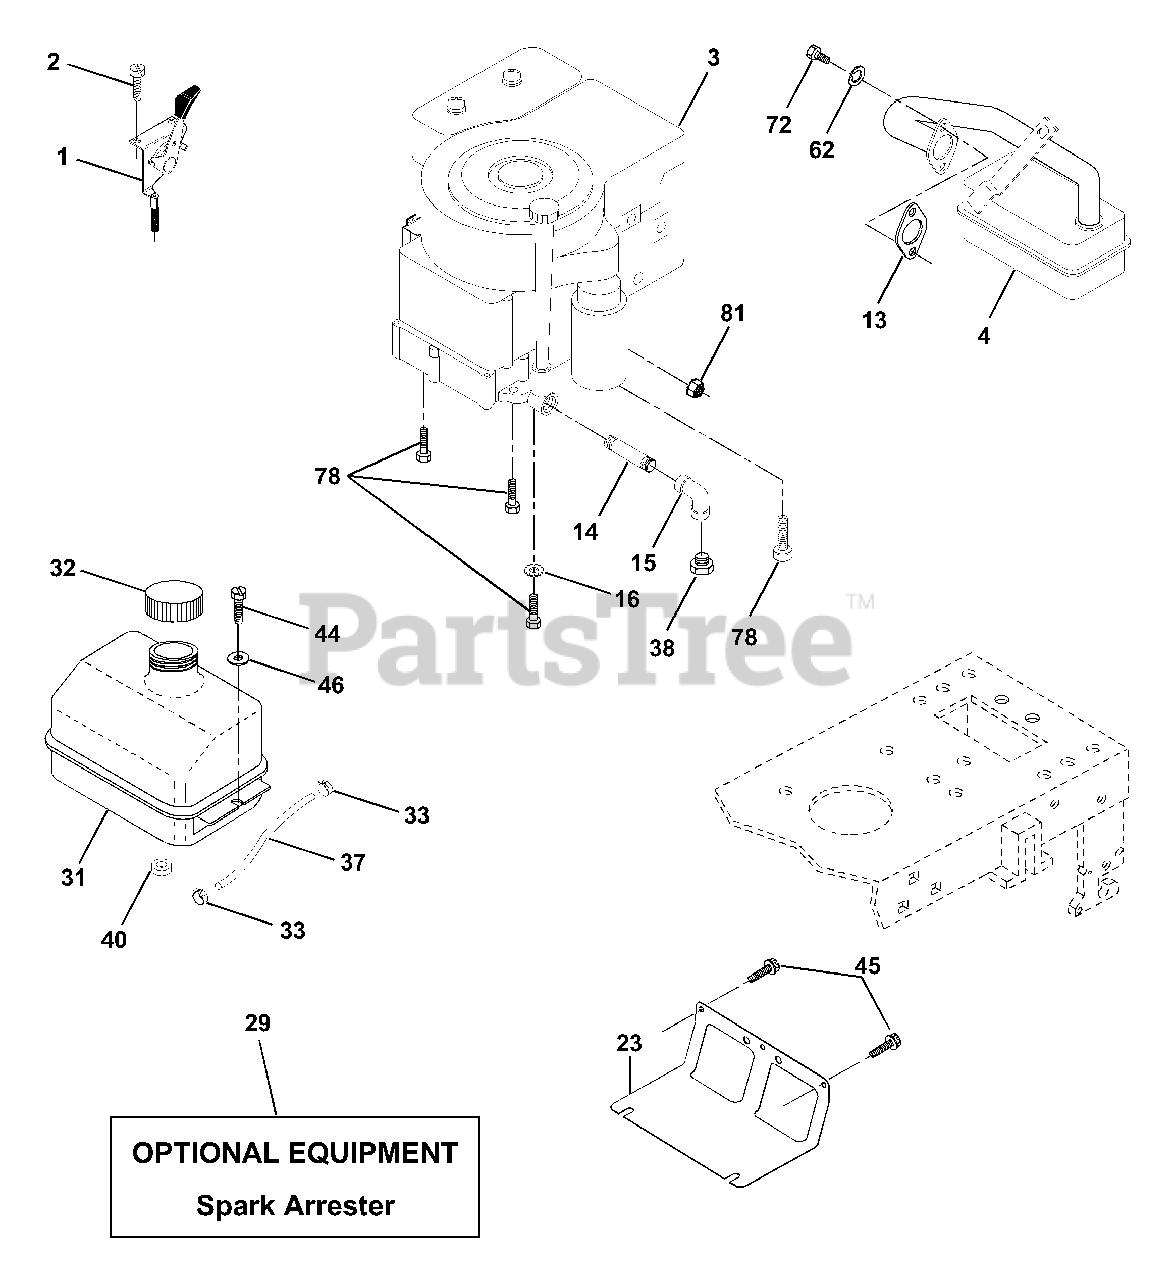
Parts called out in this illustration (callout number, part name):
1	Control Throt /Ch 23.5 Lh Flag
2	Screw Hex Thd Cut 1/4-20x5/8 T
4	Muffler Exhaust B&S Lt
13	Gasket 1 313 Id Tin Plated
14	Nipple Pipe 3/8 Npt X 3"
15	Elbow Std 90 Degree 3/8-18 Npt
16	Washer Lock Ext Tooth 3/8
23	Shield Browning/Debris Guard
29	Arrestor Spark
31	Tank Fuel 1 25 Fr
32	Cap Asm Fuel W/sym Vented
33	Clamp Hose Blk
35	Screw Thdrol 5/16-18 x 3/4 Ty T
37	Line Fuel 20"
38	Plug Oil Drain
40	Bushing Snap Nyl Blk Fuel Line
44	Screw Hexwsh Thdrol 1/4-20x3/4
45	Screw Hex Wsh Thdrol 3/8-16
46	Washer 9/32 X 7/8 X 16ga
62	Washer Lock Hvy Hlcl Spr 5/16
72	Screw Hexhd Cap 5/16-18x3/4
78	Screw Thdrol 3/8-16x1-1/4 Tytt
81	Nut Keps Hex 1/4-20 Unc
